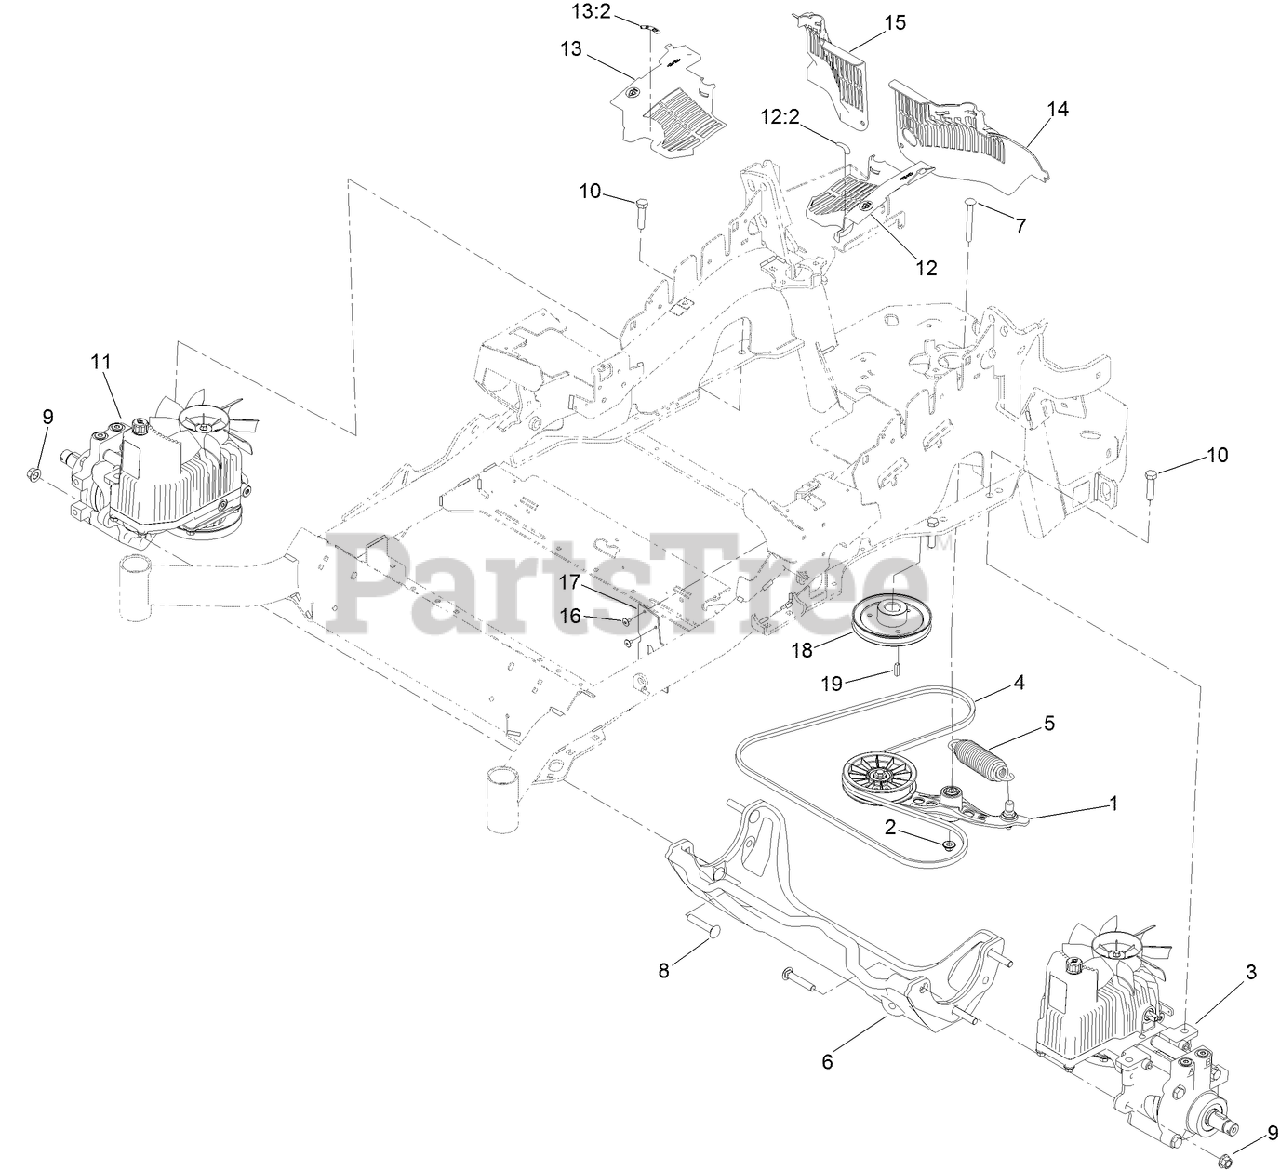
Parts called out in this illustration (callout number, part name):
1	PUMP IDLER ASM
2	NUT-FLANGE, NI
3	LH HYDRO ASM (12CC W/ SHOCK)
4	BELT
5	SPRING-EXTENSION
6	CRADLE-HYDRO
7	BOLT-SHOULDER, CARRIAGE
8	SCREW-CARR
9	NUT-LOCK
10	SCREW-HH
11	RH HYDRO ASM (12CC W/ SHOCK)
12	LH HYDRO GUARD ASM
12:2	DECAL-OIL, HYDRO
13	RH HYDRO GUARD ASM
13:2	DECAL-OIL, HYDRO
14	GUARD-HYDRO, REAR (LH)
15	GUARD-HYDRO, REAR (RH)
16	RIVET-POP
17	DEFLECTOR-AIR FLOW
18	SHEAVE
